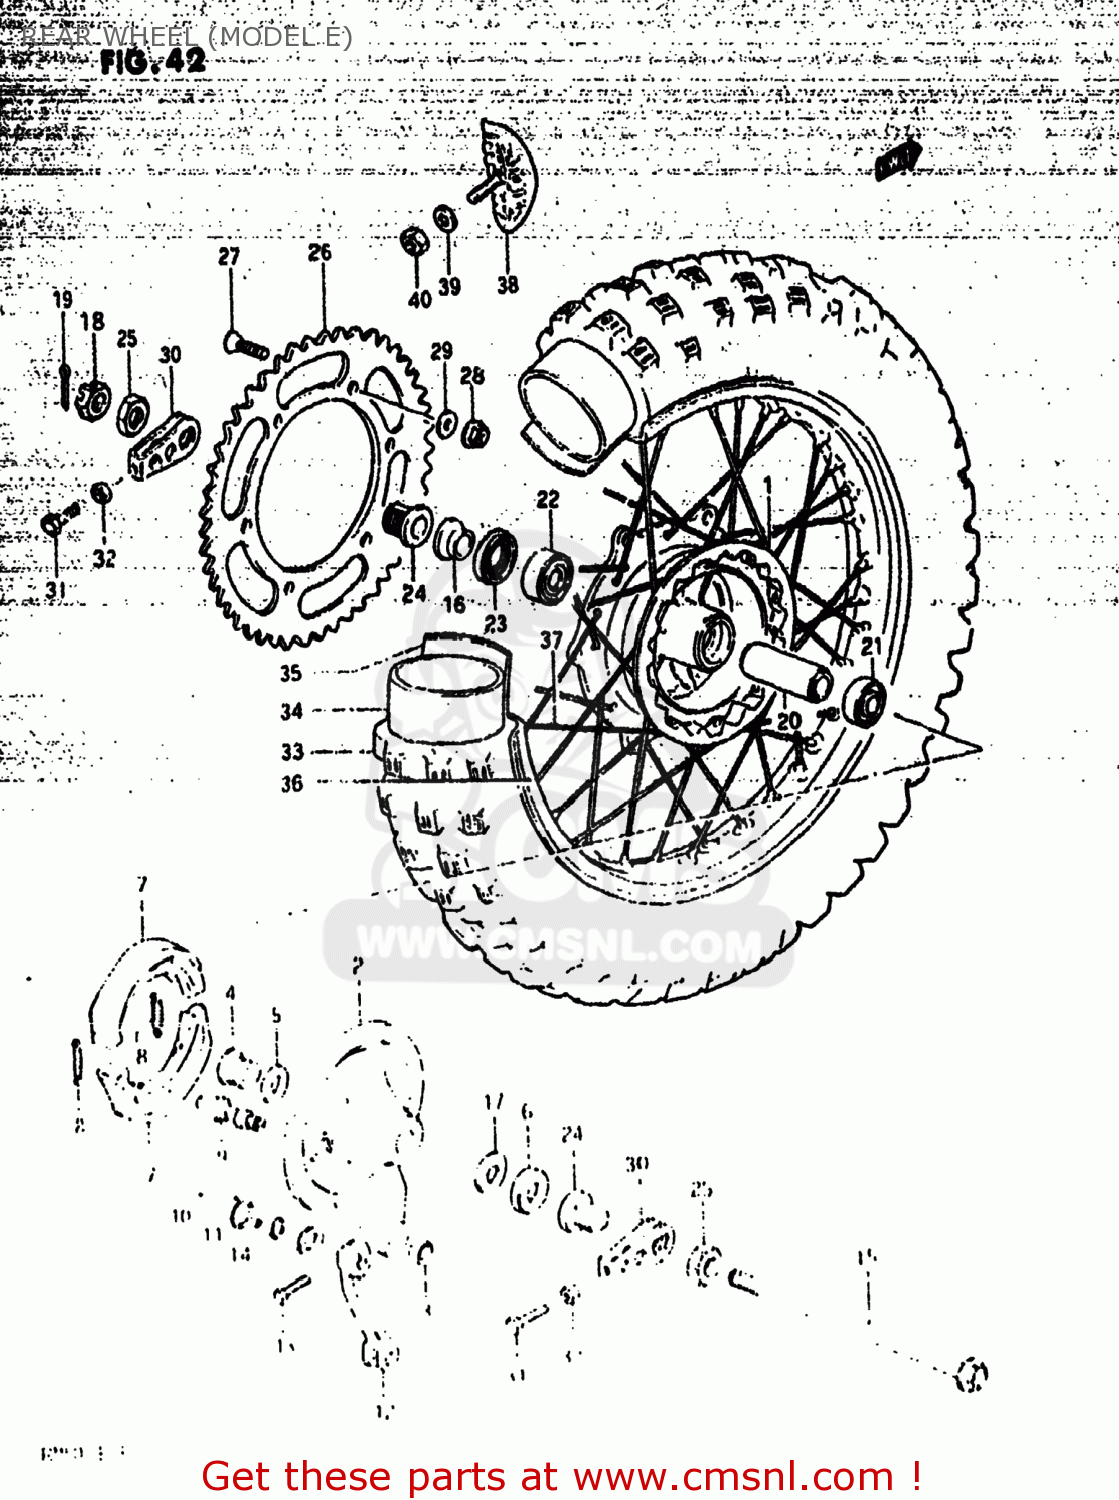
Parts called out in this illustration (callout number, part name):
1	DRUM,REAR HUB
2	PANEL SET
3	SPHERICAL BRNG,TORQUE LINK
4	SPACER,REAR HUB PANEL
5	SEAL,OIL(24X31X5)
6	CVR,RR BRAKE AHR PNL DUST SEAL
7	SHOE,BRAKE
8	SPRING,BRAKE SHOE
9	CAM,FR BRAKE
10	SPRING
11	O RING(D:2.5,ID:11.4)
12	LEVER,REAR BRAKE CAM
13	BOLT
14	WASHER(12.5X20X1)
15	AXLE,REAR
16	SPACER,REAR AXLE,LEFT
17	WASHER
18	NUT
19	PIN,COTTER
20	SPACER,REAR HUB BEARING
21	BEARING
22	BALL BEARING 17X47X22
23	OIL SEAL (25X47X7.5)
24	SPACER,CHAIN ADJUSTER
25	NUT
26	SPROCKET,REAR (NT:46)(AL)
27	SCREW(8X40)
28	NUT
29	WASHER
30	ADJUSTER,CHAIN
31	BOLT
32	NUT
33	TIRE 140/80-18
34	TUBE ASSEMBLY,WHEEL,INNER
35	PROTECTOR,INNER TUBE
36	RIM,REAR WHEEL (2.50X18)(
37	SPOKE SET,REAR WHEEL
38	STOPPER,BEAD
39	WASHER
40	NUT
